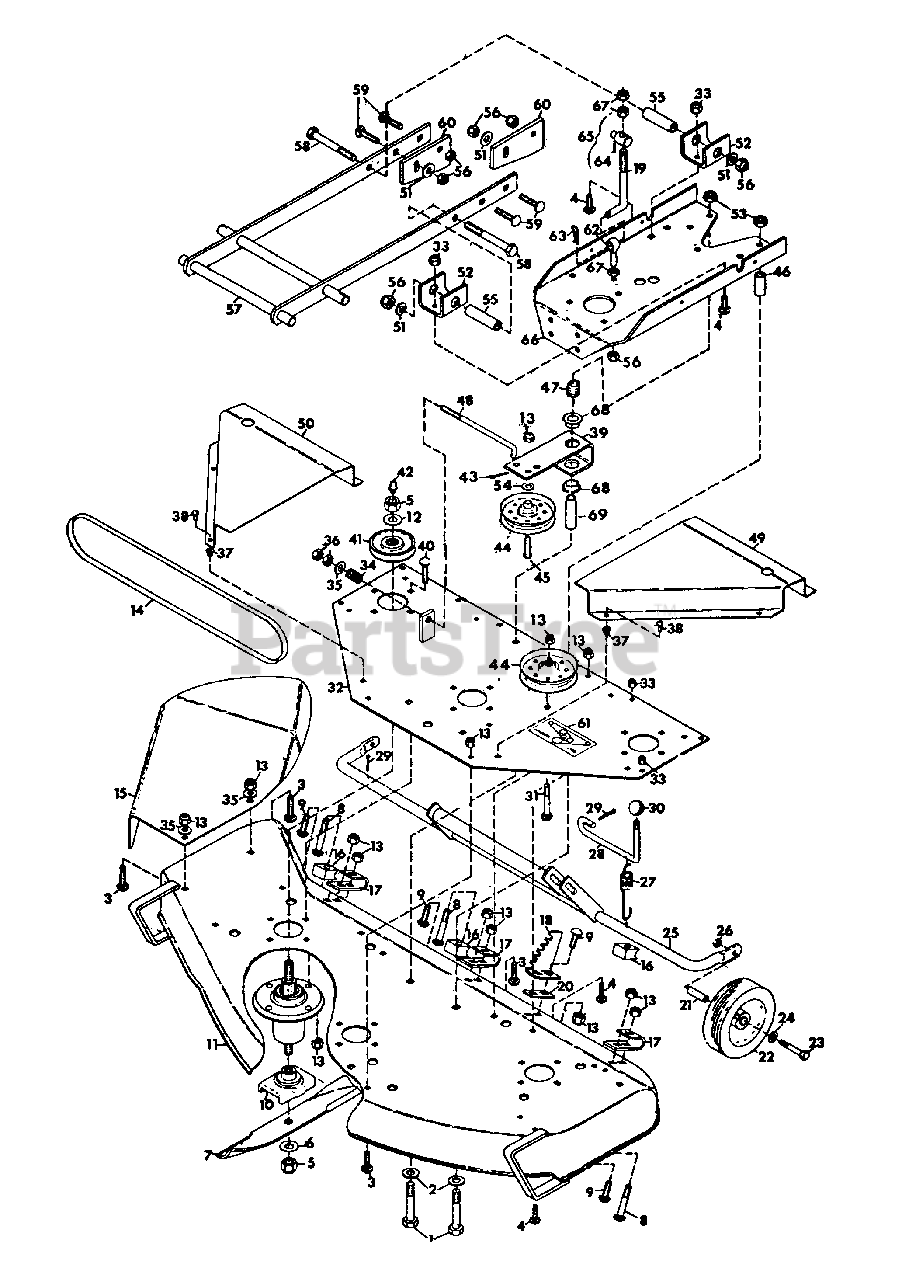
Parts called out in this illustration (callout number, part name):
1	BOLT, HEX 1/2-13X3.75
2	WASHER, FLAT .531X1.062X.095
3	BOLT, 3/8-16X.75 RD. HD. SQ. NK.
4	BOLT, 5/16-18X.75 RD. HD. SQ. NK.
5	NUT, LOCK 5/8-11
6	WASHER, FLAT .656X1.312X.095
7	BLADE
8	BOLT, 3/8-16X2 RD. HD. SQ. NK.
9	BOLT, 3/8-16X1 RD. HD. SQ. NK.
10	CRADLE, BLADE
11	WELDMENT, 50 INCH DECK
12	WASHER, FLAT .687X1.300X.122/.146
13	NUT, LOCK 3/8-16
14	BELT, V .500X.312X126.3
15	SHIELD, SAFETY EXTENSION
16	STOP, NYLON
17	BRACKET, AXLE SUPPORT
18	BRACKET, HEIGHT ADJUST
19	ROD, LIFT
20	SHIM, MOWER HT. ADJ. BKT.
21	BUSHING, .750X.375X1.785
22	WHEEL, GAUGE
23	BOLT, HEX 3/8-16X2.5
24	WASHER, FLAT .436X1.375X.083
25	WELDMENT, AXLE PIVOT
26	NUT, JAM 3/8-16 HEX
27	SPRING, 40 AND 50 INCH MOWER
28	LEVER, HEIGHT ADJUST
29	PIN, COTTER .125X1.250
30	KNOB, ADJUSTMENT CONTROL
31	BOLT, 3/8-16X1.75 RD. HD. SQ. NK.
32	WELDMENT, DECK SUPPORT PLATE
33	NUT, LOCK 5/16-18
34	SPRING, COMP. TYPE 1X.78X338 LB/IN
35	WASHER, FLAT .406X.812X.065
36	NUT, HEX 3/8-24
37	GROMMET, PLASTIC
38	SCREW, MACH. 1/4-20X.5
39	ARM, IDLER PIVOT
40	BOLT, 3/8-16X1.25 RD. HD. SQ. NK.
41	SHEAVE, SPINDLE
42	FITTING, LUBE 1/8
43	PIN, COTTER 3/32X1.000
44	SHEAVE, IDLER
45	BOLT, HEX 3/8-16X2
46	SPACER, .510X.840X2.43
47	SPRING, COMP.
48	ROD, IDLER
49	COVER, PULLEY L.H.
50	COVER, PULLEY R.H.
51	WASHER, FLAT .531X1.250X.100
52	SUPPORT, MOWER PIVOT
53	NUT, LOCK 1/2-13
54	SPACER, IDLER .406X.750X.188
55	BUSHING, PIVOT .510X.750X2.020
56	NUT, LOCK 1/2-13
57	WELDMENT, PIVOT ARM
58	BOLT, HEX 1/2-13X3.00
59	BOLT, 1/2-13X1.25 RD. HD. SQ. NK.
60	PLATE, ADJUSTMENT
61	DECAL, BELT INSTALLATION
62	BOLT, EYE
63	COTTER, HAIR PIN
64	PIN, GROOVE .125X.625
65	ASSEMBLY, MOWER LIFT PIVOT
66	SUPPORT, GEAR HOUSING
67	NUT, JAM 1/2-13
68	BUSHING, NYLON .760X1.00X.600
69	SPACER
